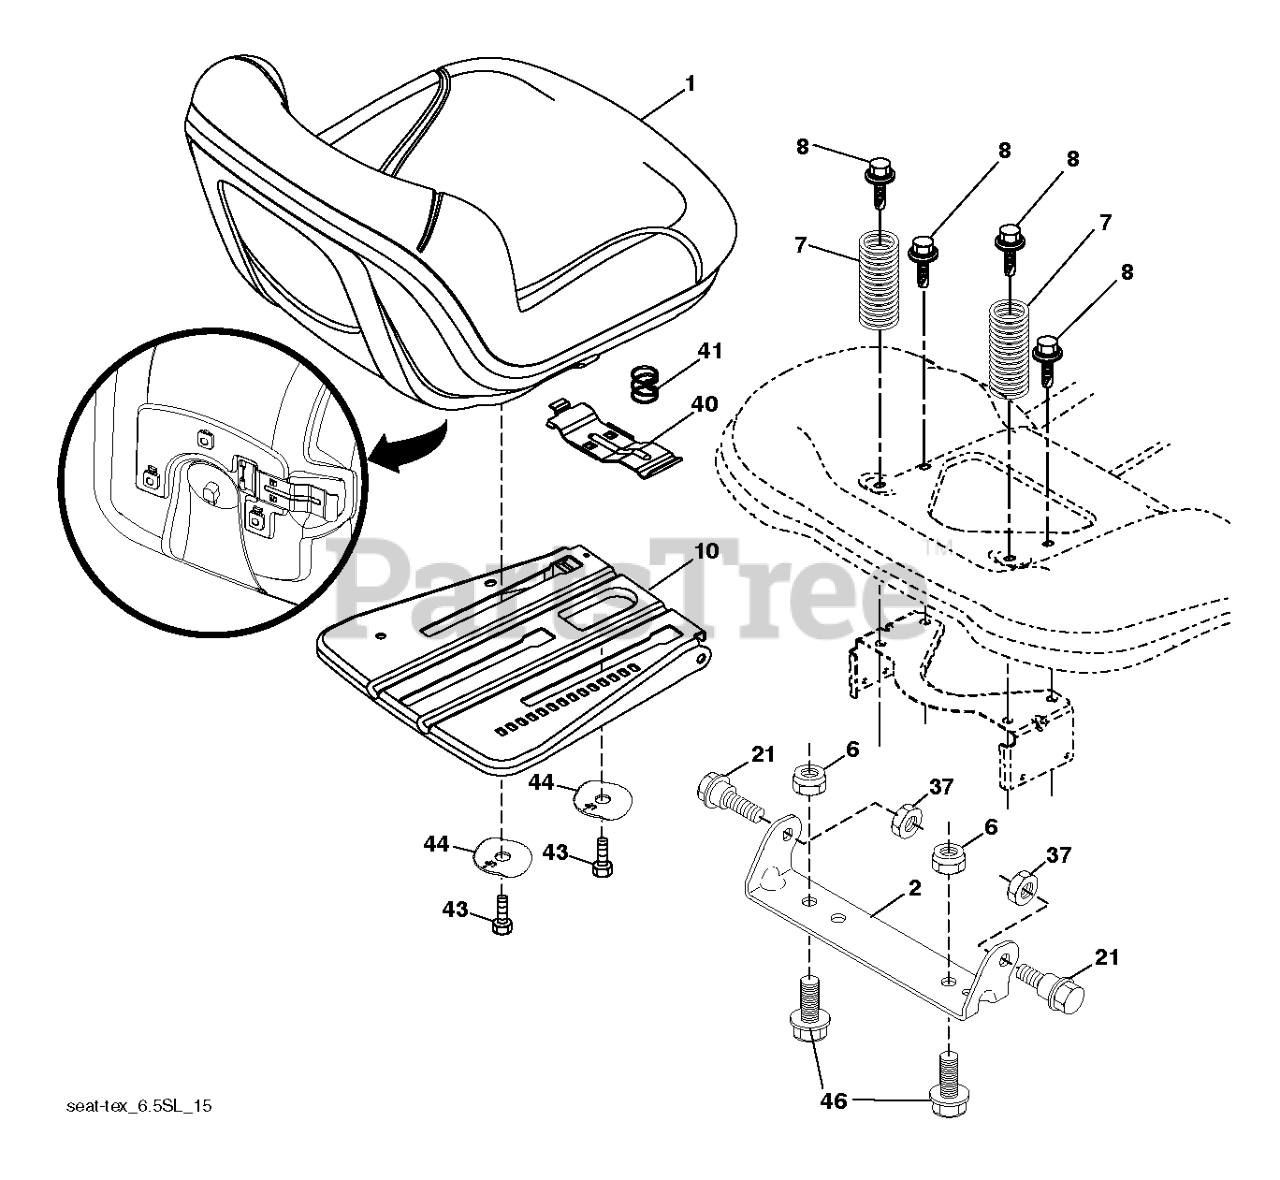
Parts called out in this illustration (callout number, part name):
1	SEAT.TG150.BLK.NLOGO.
2	BRKT.PIVOT.FENDER
6	NUT
7	SPRING.COMPRESS.SEAT.TAPERED
8	BOLT, 5/16-18 X 1 3/4
10	PLATE.PNT.SEAT.SLIDE.3PT.EDIP
21	BOLT.5/16-18X5/8.SHOULDER
37	NUT.71038.31-18.HEX.NYLOCK
40	HANDLE.SLIDE.SEAT.TEX.BLACK
41	SPRING.LATCH.SEAT.TEX
44	WASHER 13/32 X 2-3/8 X 12GA
46	BOLT.3/8-16X1;1.25OD.WSHR.SEMS
